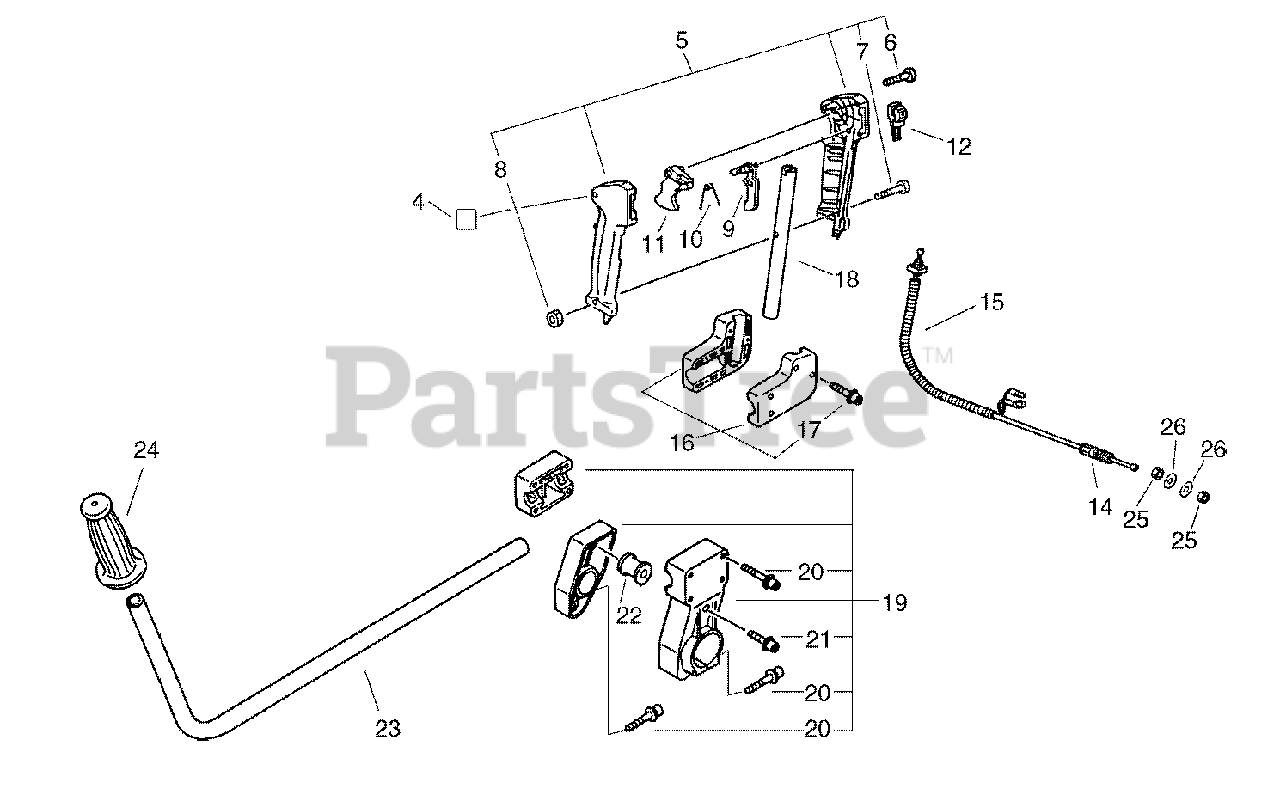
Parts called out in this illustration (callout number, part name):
4	LABEL, STOP
5	CONTROL HANDLE KIT
6	SCREW 3×25
7	SCREW 5×30
8	NUT M5
9	LOCKOUT, THROTTLE
10	SPRING, TORSION
11	TRIGGER, THROTTLE
12	SWITCH, ON-OFF
14	CABLE, THROTTLE
15	TUBE
16	BRACKET, HANDLE
17	BOLT 5×25
18	HANDLE, REAR
19	BRACKET, HANDLE
20	BOLT M5×35
21	BOLT 5×14
23	HANDLE, LEFT
23	HANDLE, FRONT
24	GRIP, HANDLE
26	WASHER 6.5×11.5×0.8
